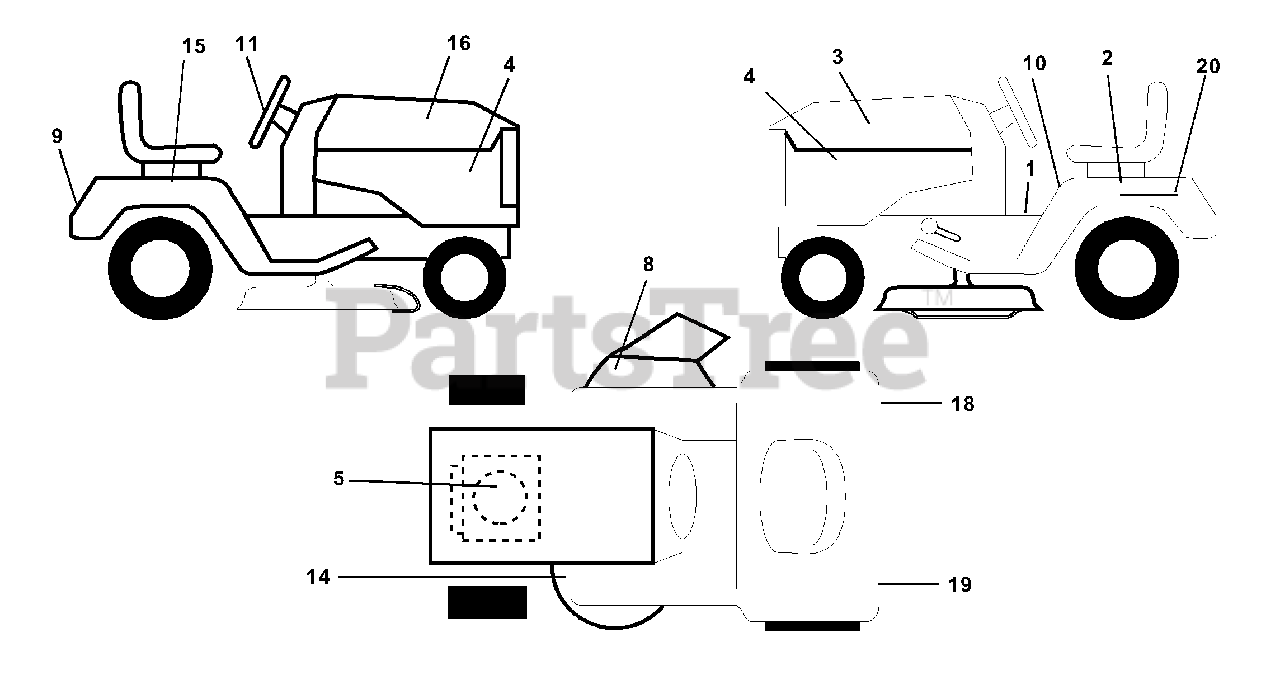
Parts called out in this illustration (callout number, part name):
2	Decal Fender Side Lh
3	Decal Hood LH
4	Decal Side Panel Logo
5	Decal HP Engine
8	Decal Warning Mult-Language
9	Decal Fender Logo
10	Decal Fender Danger E/F
11	Decal Ins Strg Whl
14	Decal V-Belt Schematic
16	Decal Hood Rh
18	Decal Fender Reflector RH
19	Decal Fender Reflector LH
20	Decal Bat Dan/Psn
